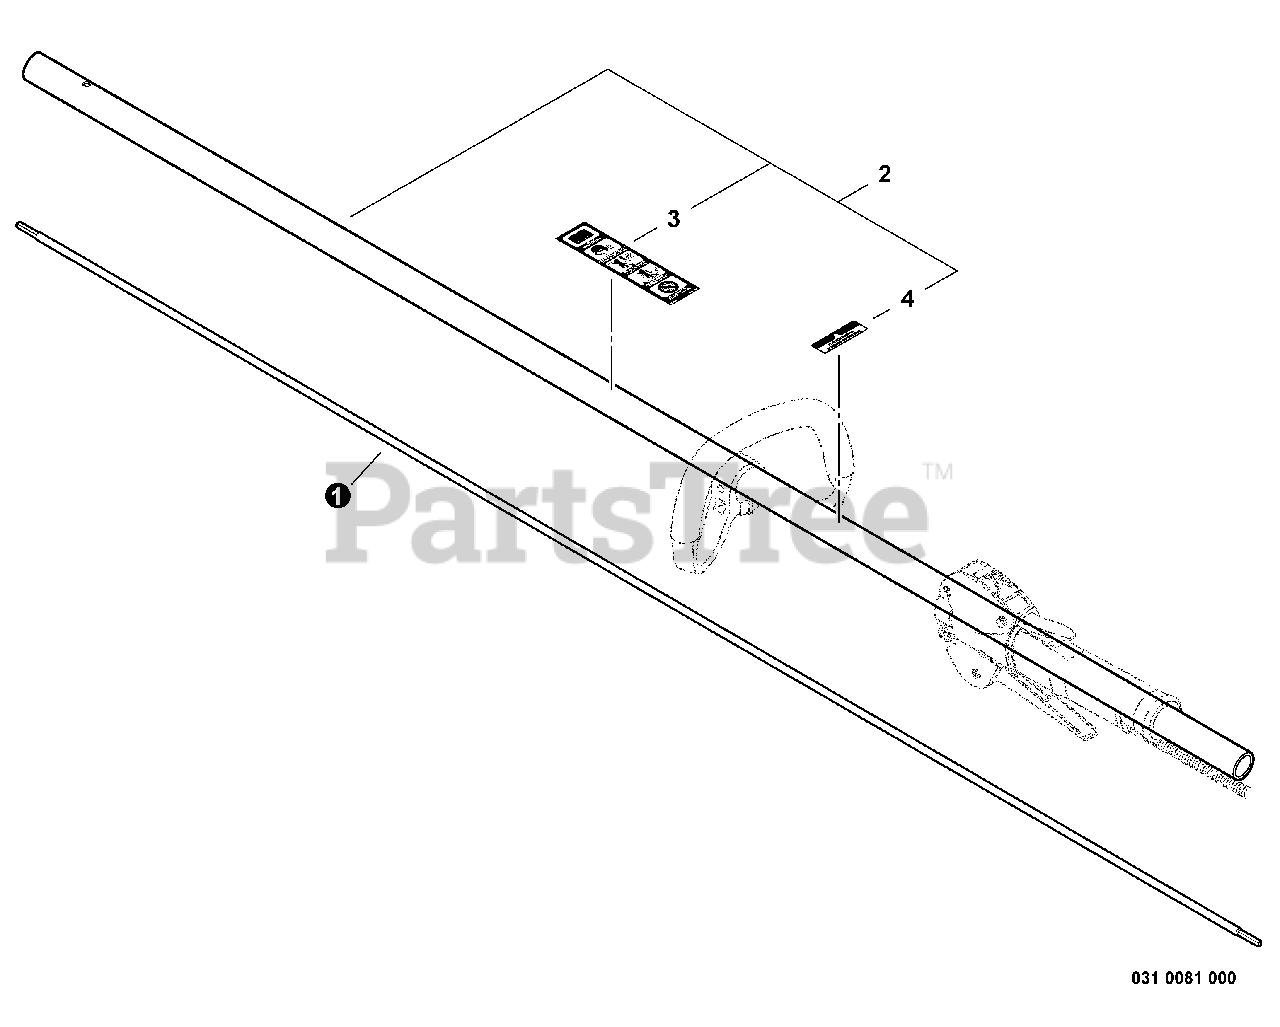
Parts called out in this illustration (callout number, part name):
1	DRIVESHAFT - SOLID
2	MAIN PIPE ASSY
3	LABEL - CAUTION
4	LABEL - HANDLE LOCATION
